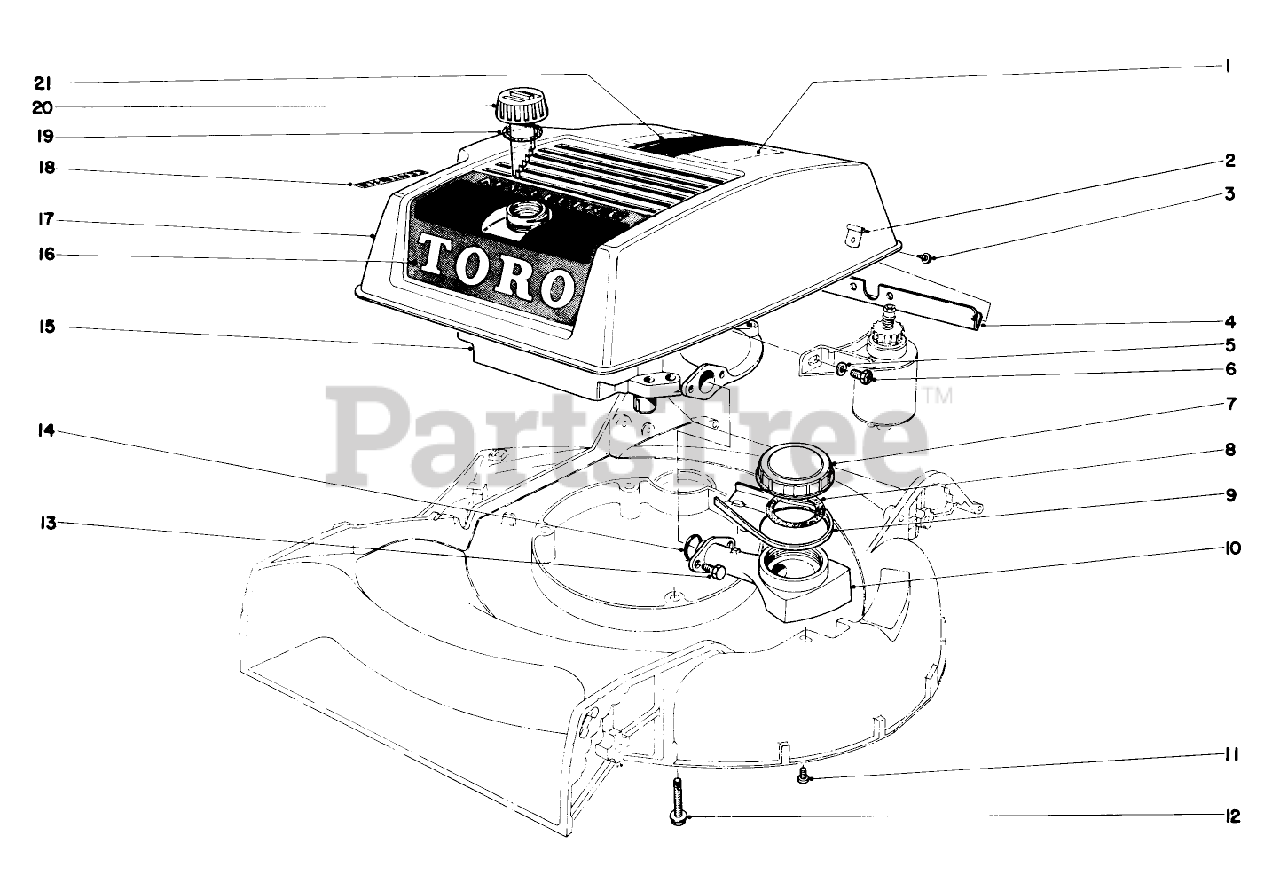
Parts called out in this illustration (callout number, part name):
1	Decal-Maintenance
2	Hinge
3	SCREW-HWHTF
4	Shroud Bracket
5	WASHER-FLAT
6	Screw
7	Oil Gauge Cap
8	VISUAL OILER GASKET
9	Spout
10	Oil Gauge
11	Screw
12	3/8-16 X 2-3/4 CAPSCR
13	Screw
14	O RING
15	Engine
16	Decal
17	Shroud
18	Decal, Air Cleaner
19	Gasket
20	Gas Cap
21	Decal
